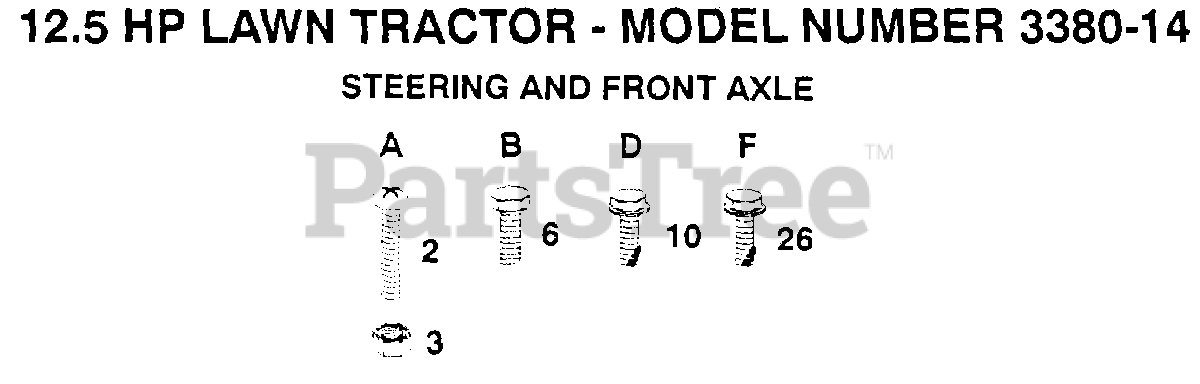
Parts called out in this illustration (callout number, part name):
2	SCREW
6	SCREW LT
10	SCREW LT
26	SCREW
